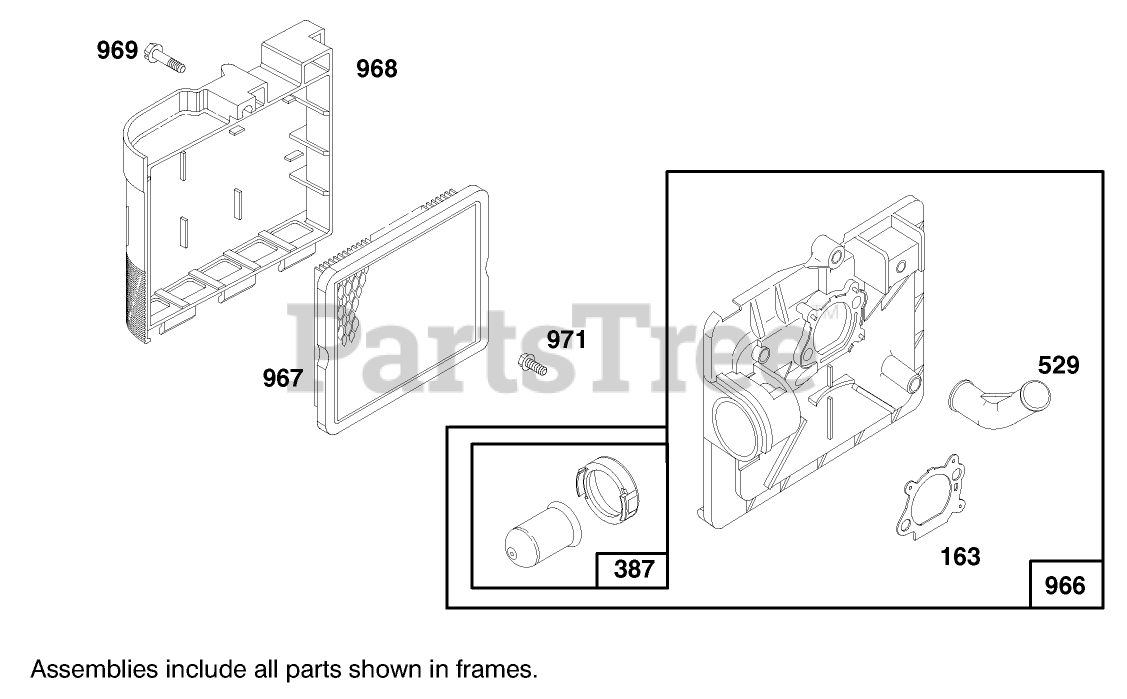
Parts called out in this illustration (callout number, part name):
163	Gasket-Cleaner, Air
387	CarburetorPrimer
529	Grommet
966	Base-Primer, Air Cleaner
967	Filter-Air Cleaner, Cartridge
968	Air Cleaner Cover
969	Screw-Cover Mt.
971	Screw-Air Cleaner
